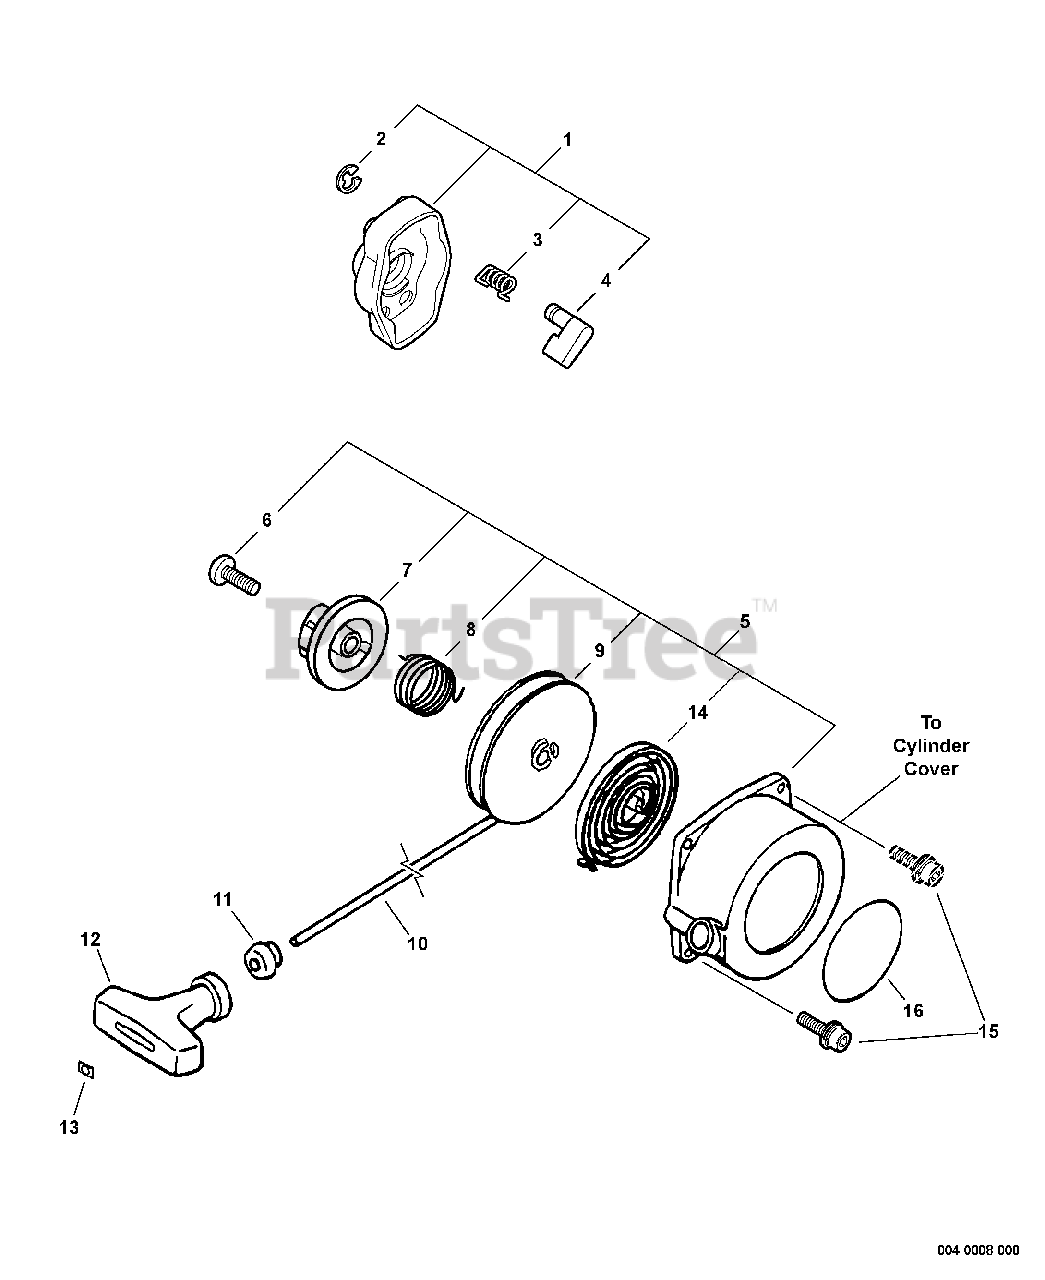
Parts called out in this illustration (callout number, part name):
1	STARTER PAWL ASSY
2	RING, RETAINING - 4
3	SPRING, RETURN
4	PAWL, STARTER
5	STARTER ASSY
6	SCREW
7	PLATE, CAM
8	SPRING, DAMPER
9	REEL, ROPE
10	ROPE, STARTER - 3X700
11	GUIDE, ROPE
12	GRIP, STARTER
13	RETAINER, ROPE
14	SPRING, REWIND
15	SCREW - 4X16
16	LABEL - ECHO -- i-30
